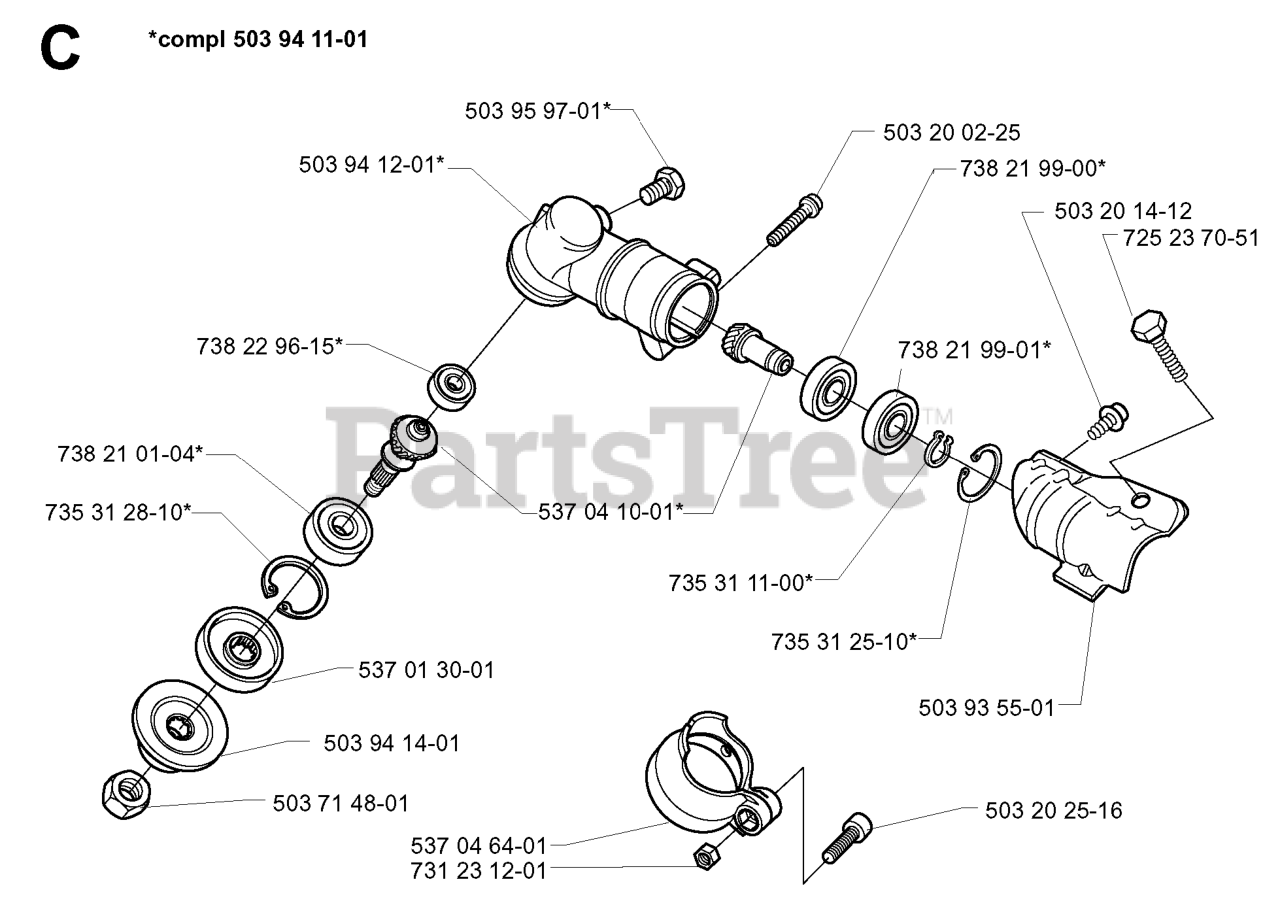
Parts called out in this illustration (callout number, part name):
2	SPRING,BRAKE RETURN
3	PULLEY
4	RETAINING RING LT
5	STRAP TORQUE
6	SCREW 5/16"
8	ROD SHIFT FENDER ADJUST LT
9	CLUTCH.ELECTRIC.OGURA.EURO.
10	PIN COTTER
11	WASH-SHFT PLT LT
13	BOLT 1/4-28X3/4
14	LOCKWASHER
15	BOLT HEX 5/16-18 GR 5
16	NUT.71038.31-18.HEX.NYLOCK
19	NUT
20	BOLT HEX 7/16-20X4-1/4"
21	KNOB.DUCKHEAD.1/2
22	ROD
24	NUT
25	SPRING ROD LT
26	WASHER
27	COTTER PIN
28	ROD, PARKING BRAKE
29	CAP
30	BRKT, MOUNT TRNSAXLE
34	SHAFT, FOOT PEDAL
35	BEARING.NYLON
37	DRIVE PIN
38	PULLEY.FLAT
42	WASHER
47	IDLER PULLEY
48	BELLCRANK, CLUTCH
49	RETAIN BELT
50	BOLT.3/8-16X1.50
53	LINK.CLUTCH.7.66.2005
55	SPRING, RETURN LT
56	SCREW.3/8-16
57	V-BELT.KEV.111"
62	PEDAL COVER T
63	PULLEY.ENGINE.CVX.LT
65	LOCKWASHER
66	KEEPER BELT ENGINE
74	SPACER AXLE
77	SQUARE KEY
79	KEY STD (1373) DANA
82	SHIFT SPRING
83	WASHER
96	RETAINER M
120	NUT LOCK FLG 3/8-16 UNC
150	BUSHING.BELLCRANK.GRD.DR
151	WASHER 12/32X2X10GA
156	WASHER.SRRTD.5/16
158	BRACKET
159	RB HUB.SHIFT
161	BOLT
162	NUT.CROWNLOCK.1/4
165	RP BRACKET
166	CAPSCREW.HXHD.FLG.5/16-18X.625
167	BRACKET.SUPT.SHIFT.CRD
168	BOLT.SHOULDER.5/16-18X
172	SHAFT
181	BRACKET
182	BELT GUIDE
183	PULLEY.V-IDLER.GRND.DR
187	BOLT.5/16-18X1.25
207	WASHER NYL
214	LEVER
243	BRACKET, ANTI-ROTATION
254	SCREW 3/8-16X1
255	SHAFT
258	CLIP RETAINER
261	FLAT IDLER PULLEY
263	SCREW, 3/8-16X3/4
266	PROTECTOR
268	GUARD MUFFLER
275	WASHER
292	SPACER
295	PULLEY IDLER COMPOSITE
